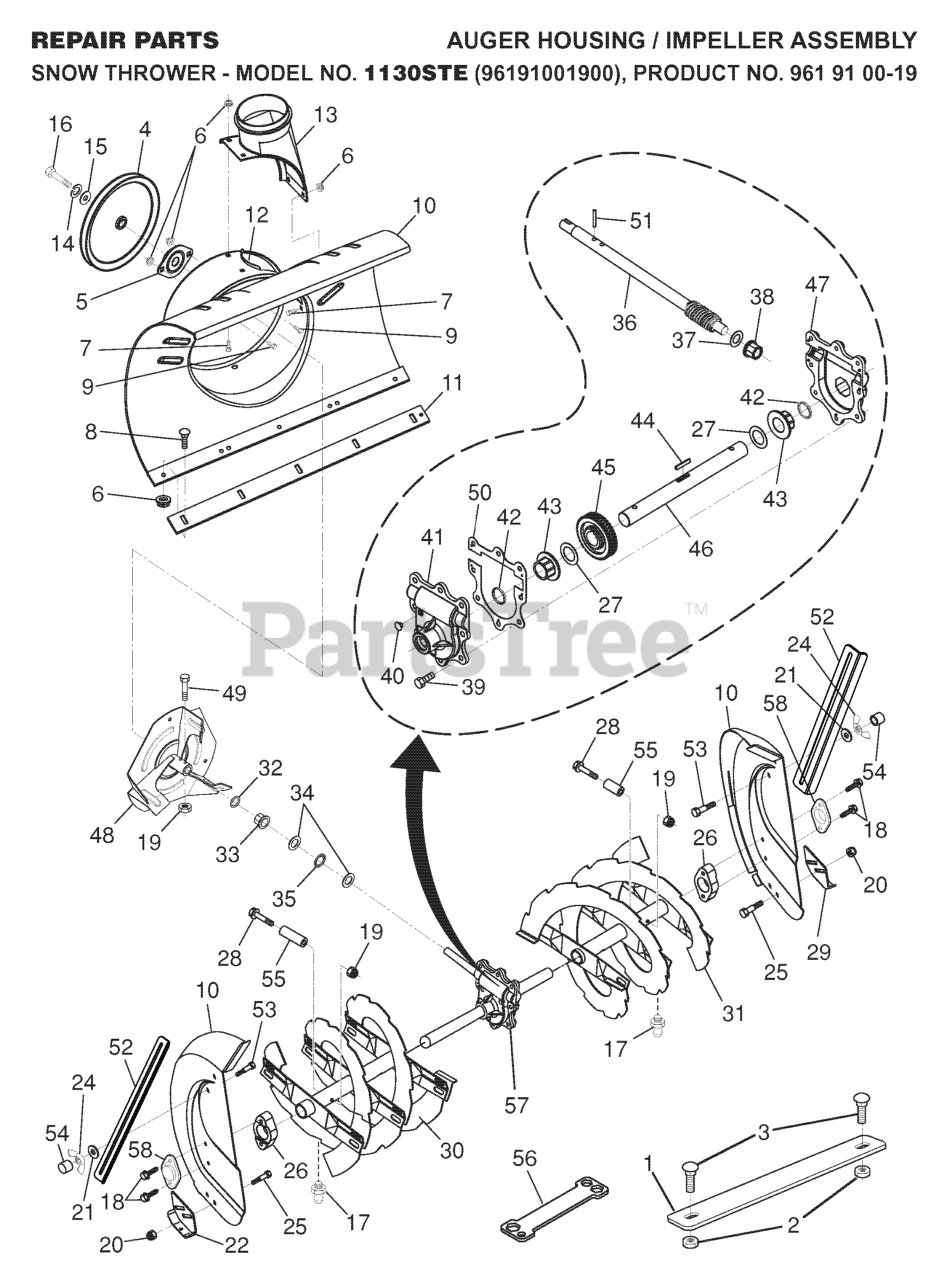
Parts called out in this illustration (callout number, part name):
2	NUT.LOCK.5/16-18
3	BOLT.CARRIAGE.5/16-18
4	PULLEY, IMPELLER
5	BEARING FLANGE
6	NUT.FLANGE.5/16
7	BOLT.CARRIAGE.5/16-18X
8	BOLT
9	BOLT, HEX HEAD 5/16-18
10	HOUSING, AUGER
11	BAR, SCRAPER
12	BRACKET, CORNER DISCHARGE
13	BASE DISCHARGE CHUTE
14	WASHER, FLAT
15	WASHER.LOCK.HVY.HLCL.SPR.5/16
16	CAPSCREW.HX.HD.5/16-18X1.00.NY
17	GREASE FITTING
18	SCREW, HEX HD 5/16X1
19	LOCKNUT.NYLOC.1/4-20
20	NUT.FLANGE.5/16
21	WASHER.12021.438X.75X.06.PLS
22	SKID PLATE RH
24	NUT WING PM
25	BOLT
26	BEARING RETAINER, PLASTIC
27	WASHER TRUST 1"
28	BOLT, SHEAR
29	SKID PLATE LH
30	AUGER ASSEMBLY, RH
31	AUGER ASSEMBLY, LH
33	BUSHING, FLANGE 3/4
34	WASHER, THRUST 3/4
35	BEARING TRUST 3/4 NTA-1220
36	SHAFT, IMPELLER
37	WASHER, THRUST 5/8
38	FLANGE BUSHING-5/8
39	HEX SCREW-5/16 X 3/4
40	CASE PLUG
41	GEARBOX HOUSING-RH
42	OIL SEAL
43	FLANGE BUSHING-1"
44	KEY, SQUARE 1/4 X .875
45	WORM GEAR
46	AUGER SHAFT
47	HOUSING.GEARBOX.LH(SERVICE)
48	IMPELLER ASSY
49	SCREW.HEX.HD1/4-20X
50	GEARBOX GASKET
51	PIN, ROLL 3/16 X 1-1/8
52	DRIFT CUTTER BAR
53	BOLT
54	STOP.11261.PLASTIC.30X50L.RED
55	SPACER.3943.SLEEVE.250X.47
56	RP WRENCH, SNOWTHROWER
57	GEARBOX.ASSEMBLY.AUGER
58	BEARING.BALL.AUGER.SHAFT
